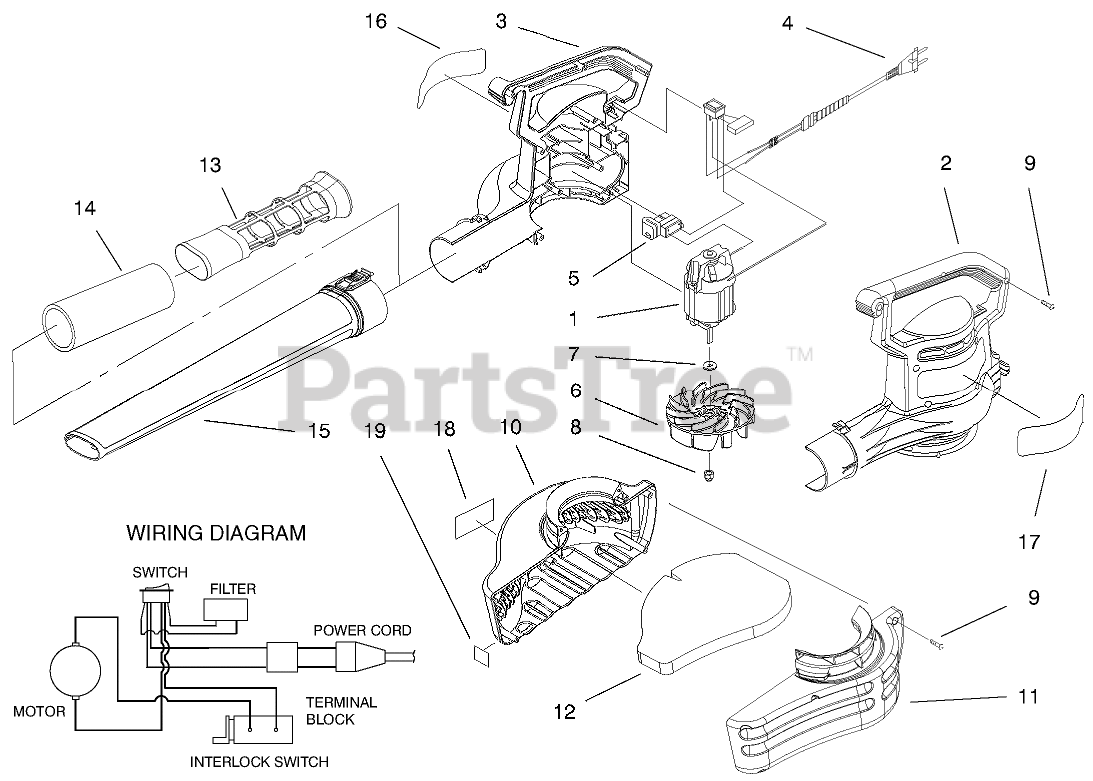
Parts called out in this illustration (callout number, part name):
1	MOTOR - 2.25" STACK 230V
2	HOUSING, LH - 230V BLOWER
3	HOUSING, RH - 230V BLOWER
4	Harness Assembly (Only On: 51566)
4	Harness Assembly (Only On: 51568)
5	SWITCH, INTERLOCK
6	IMPELLER - BLOWER
7	WASHER
8	NUT - IMPELLER
9	SCREW-PPH
10	INLET - QUIET, RH
11	INLET - QUIET, LH
12	FOAM - INLET
13	INSERT - QUIET
14	FOAM - INSERT
15	Tube-Blower (Only On: 51566)
16	DECAL, LOGO, SUPRBLWR
17	Decal-Warning (Only On: 51566)
17	Decal-Warning (Only On: 51568)
18	DECAL - QUIETECH
19	DECAL - 63DBA
